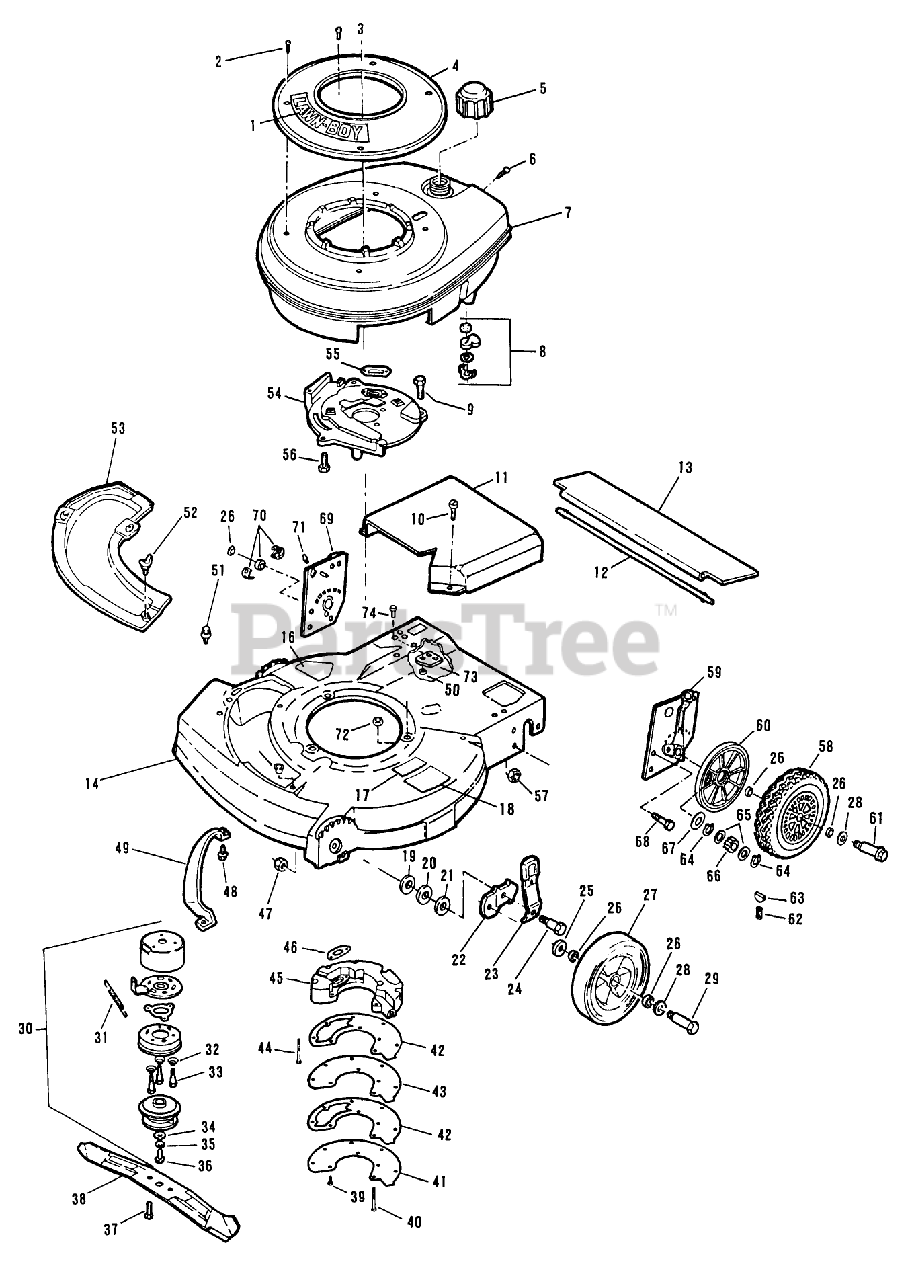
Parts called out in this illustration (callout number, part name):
2	SCREW - SELF TAPPING
3	SCREW SEMS SM
5	FUEL CAP & INSERT
6	SCREW S
8	SHUT OFF VALVE KIT
9	SCREW-HH
10	SCREW SEMS TRM HEX HD
18	PAD FOOT
19	WASHER
20	WASHER
21	WASHER
23	SPRING ARM ASM
24	BOLT
25	WASHER WROUGHT
26	WASHER
28	SPACER
29	BOLT WHEEL
31	SPRING
33	SCREW,SHOULDER SM
34	WASHER
37	SCREW SEMS
38	21" Blade
39	SCREW
42	GASKET F
47	LOCKNUT
49	BAR-TOE
50	LOCKNUT E
52	WING SCREW LAWRE
56	SCREW V
57	NUT-LOCK F
61	BOLT WHEEL
62	SPRING
63	KEY
64	RET RING
65	SPACER/GR ALGHNY
66	PINION BROCKWAY
70	REAR AXLE BEARING
71	**FITTING LINCOLN
72	NUT-LOCK F
73	BOLSTER
